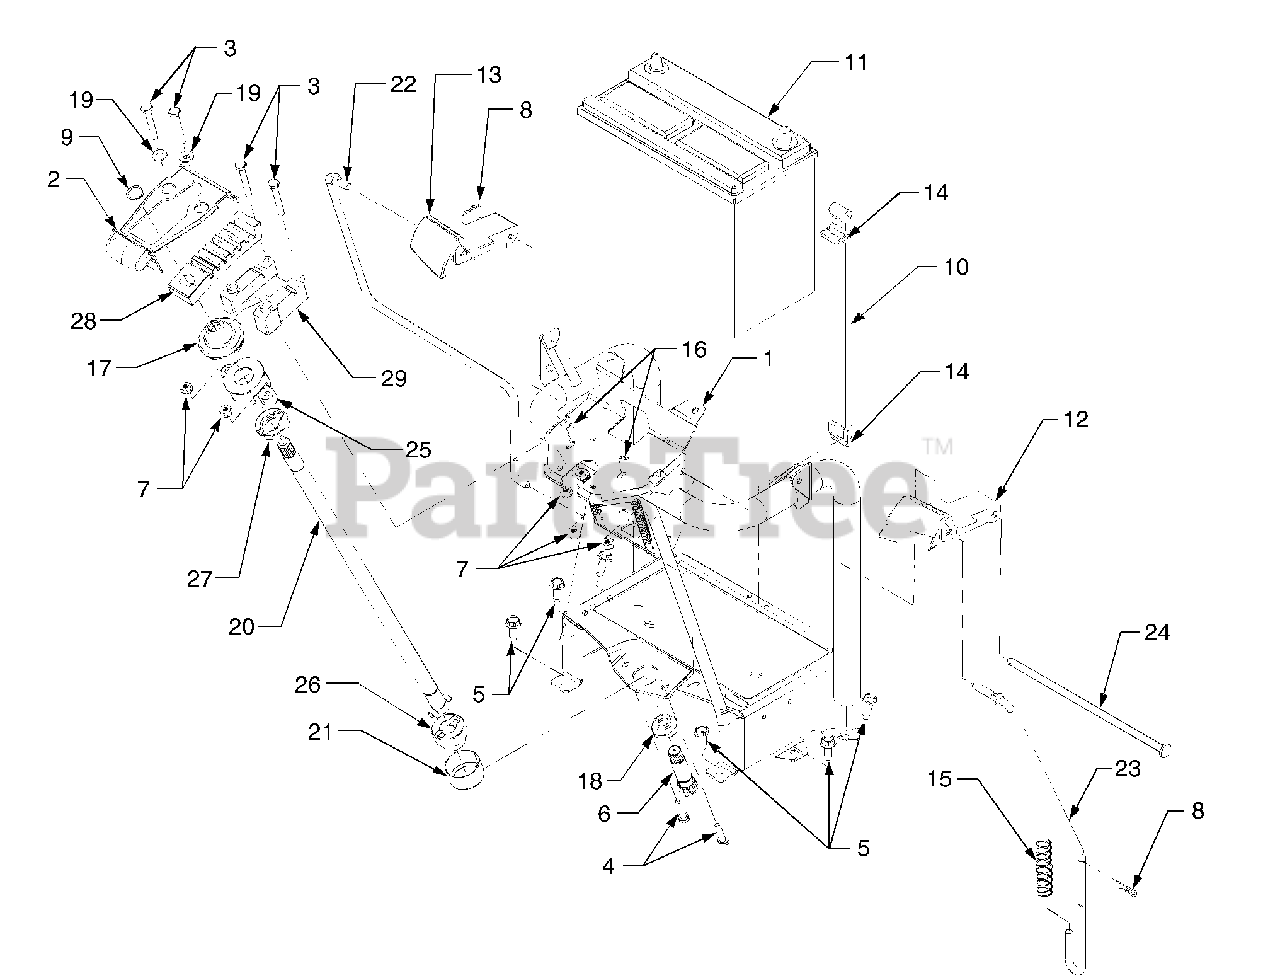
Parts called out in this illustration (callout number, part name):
3	Screw, Hex Cap 1/4-20 x 1.75 GR5
4	Screw, Hex Cap 1/4-20 x 1.0 GR5
5	Screw, Hex Wash. Hd. Tapp 5/16-18 x .75
6	Shaft, Lower Steering
7	Nut, Hex Insert Lock, 1/4-20
8	Pin, Internal Cotter
9	Ring, Retaining, .56 Dia Shaft
10	Strap, Battery
11	Battery
12	Lever, Park Brake
13	Lever, Cruise
14	Hook, Wire Rectangular
15	Spring, Compression, .676 x 2.5
16	Spring, Extension
17	Boot, Tilt Wheel Coupling
18	Boot, Shaft Cover
19	Washer, Flat, .271 x .63 x .065
20	Shaft, Upper Steering
21	Bearing, Sleeve, 1.44 x 1.5 x .812
22	Rod, Cruise Control
23	Rod, Parking Brake
24	Rod, Cruise/Brake Pivot
25	Housing, Tilt Wheel Coupling
26	Coupling Half, Bottom
27	Coupling Half, Top
28	Index, Tilt Steering
29	Block, Tilt Steering
